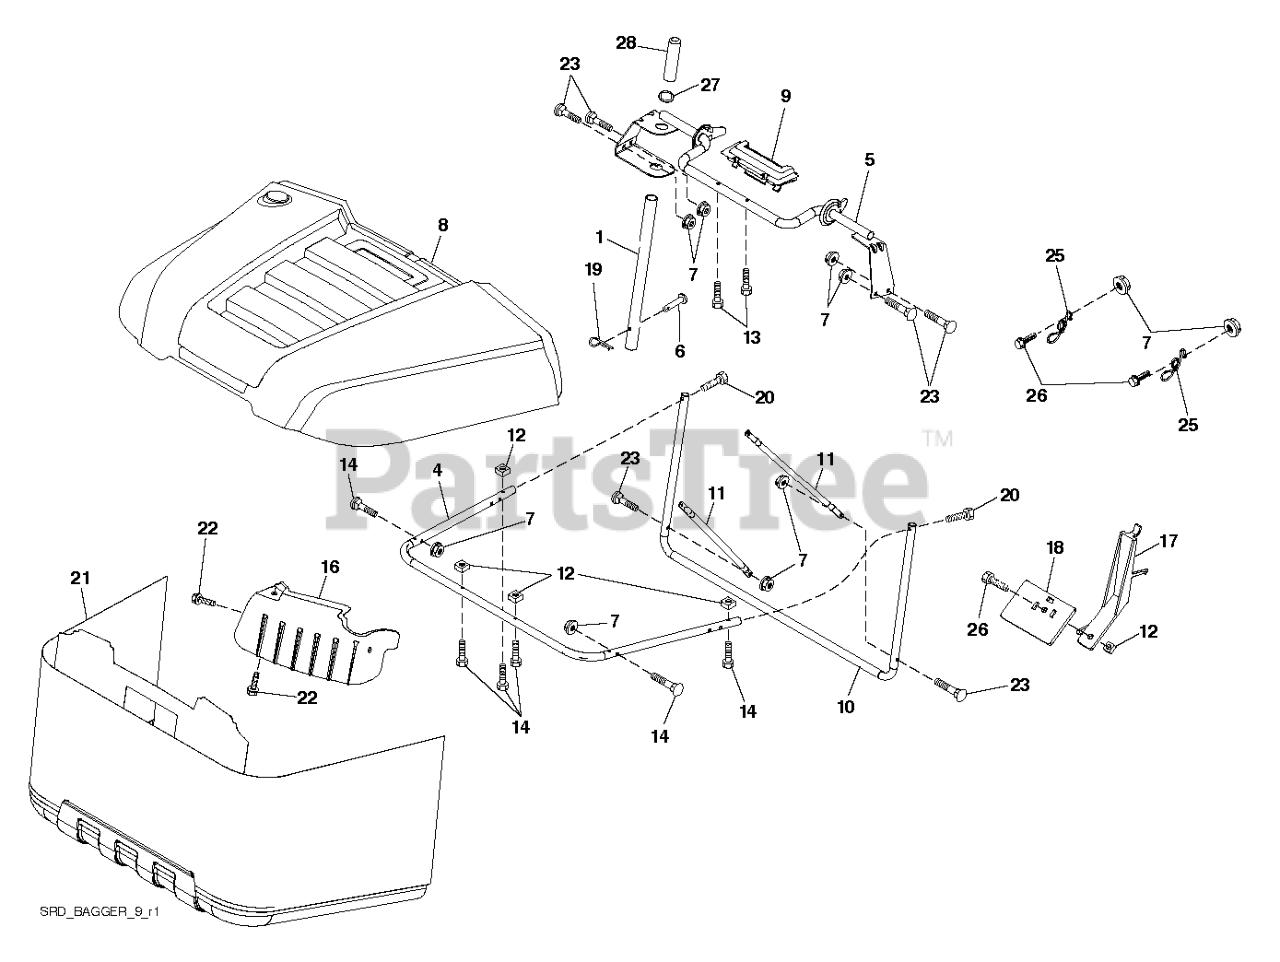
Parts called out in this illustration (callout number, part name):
1	TUBE.HANDLE.BAGGER.CRD/SRD.BLA
4	SUBASM.TOP.TUBE.TEX.CRD
5	FRAME.ASM.TOP.BAGGER.SRD
6	RIVET,DRILLED
7	NUT T
8	BAGGER.TOP.SUB.ASSEM.SRD
9	INSERT.HANDLE.BAGGER.(2 2)
10	FRAME.FRONT.SRD.BAGGER
11	TUBING.BRACE.BAGGER.SRD.BLACK
12	NUT.SQUARE.1/4
13	SCREW.1/4X1.150.HXWSH
14	BOLT.SHOULDER.HX.WSH.1/4X1.150
16	DEFLECTOR.BAGGER.SRD
17	LEVER.BAGGER.FULL.SRD.BLACK
18	PADDLE.BAGGER.FULL.SRD.BLACK
19	PIN.COTTER.5/16.BOW TI
20	SCREW.HEXCAP.1/4-20X1.375(2 2)
21	BAG.ASM.BAGGER.SRD.HUSQVA.GREY
22	SCREW.HI-LO.CONSOLE
25	SPRING.LATCH.BAGGER.SRD
26	SCREW HEX CRT
27	RB GROMMET.RUBBER.SRD
28	GRIP.HANDLE.BLACK
